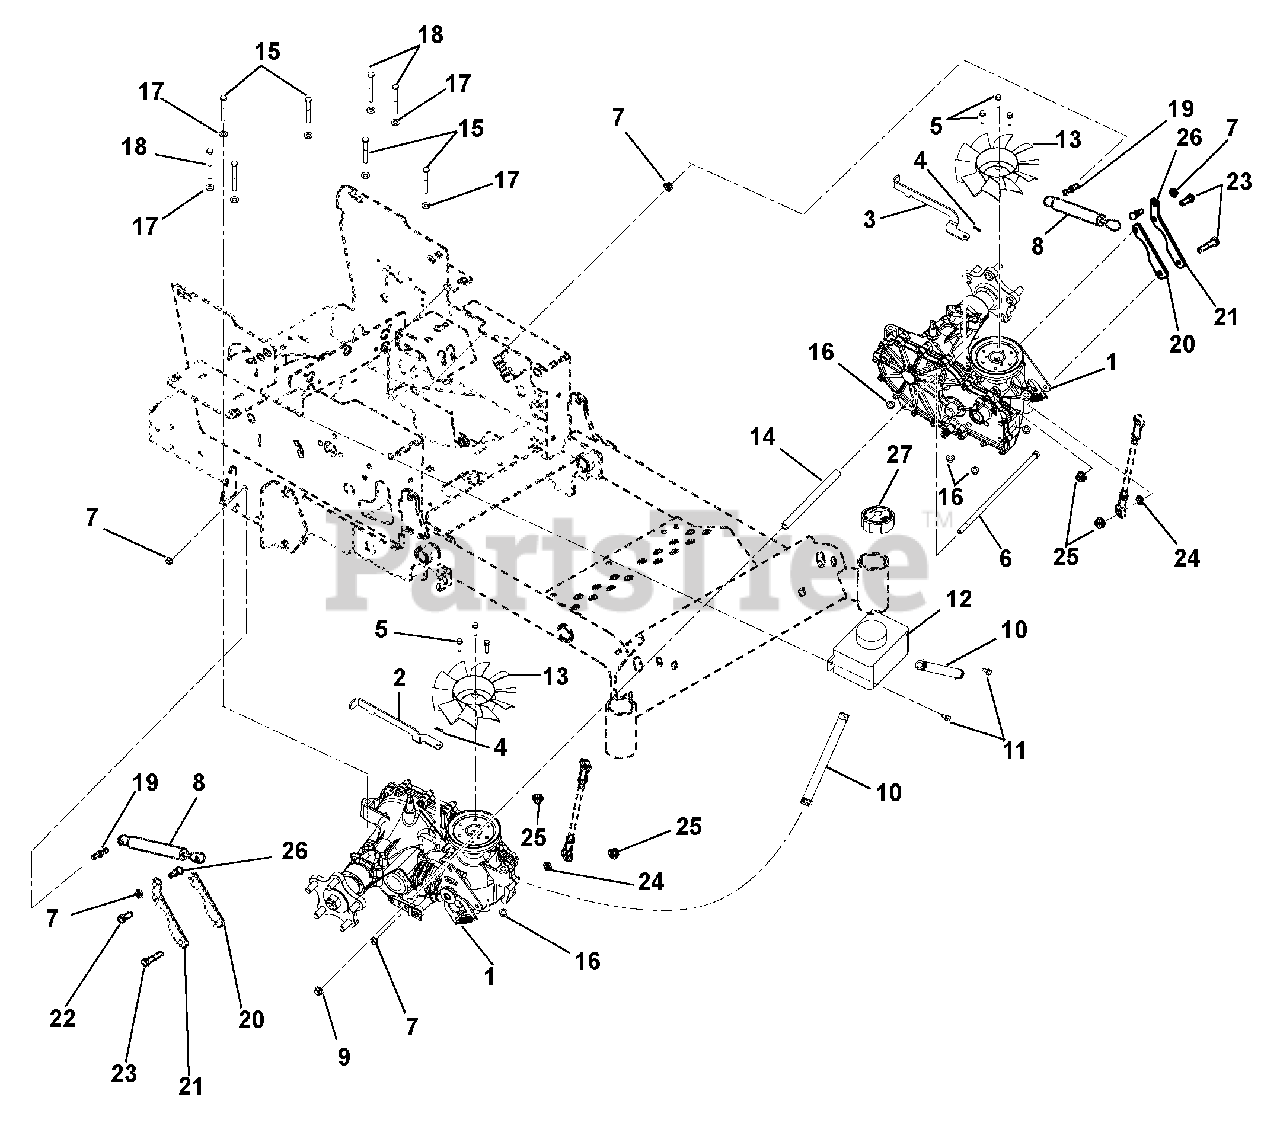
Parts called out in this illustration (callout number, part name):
1	TRANSAXLE, 3100 SERIES - LH
2	RH DUMP VALVE LEVER - BLACK
3	LH DUMP VALVE LEVER - BLACK
4	PIN-HAIR INT .06X.18X.77
5	@SCR-TAP .25-20X1.00 HWH TR YZ
6	BLT HEX, .38-16X11.00 GR5 YWZC
7	@NUT-LK-TOP-FLG .31-18 YWZC
8	DAMPER, STABILUS
9	@NUT-LK-NYL-FLG .38-16 YWZC
10	ASM, HYDRO OVERFLOW TANK HOSE
11	@SCR-TAP .25-20X.50 HWH TR YWZ
12	TANK, EXPANSION
13	FAN, 2800 SERIES COOLING
14	SPCR,.406 ID X .630 OD X 7.724
15	@BLT-HEX .31-18X2.50 GR5 YWZC
16	@NUT-LK-NYL-FLG .31-18 YWZC
17	@WSHR-FL-STL.344X.688X.065YWZC
18	@BLT-HEX .31-18X3.00 GR5 YWZC
19	STUD-BALL-THREADED
20	PLATE, CONTROL REINFORCEMENT
21	PLATE,TRANSMISSION DAMPER MTG
22	@BLT-HEX .38-16X1.00 GR5 YWZC
23	@BLT-HEX .38-16X1.75 GR5 YWZC
24	@WSHR-LK .38X.094 REG YWZC
25	@NUT-LK-NYL-FLG .38-16 YWZC
26	STUD- BALL
27	CAP, HYDRO RESERVOIR REPLAC.
